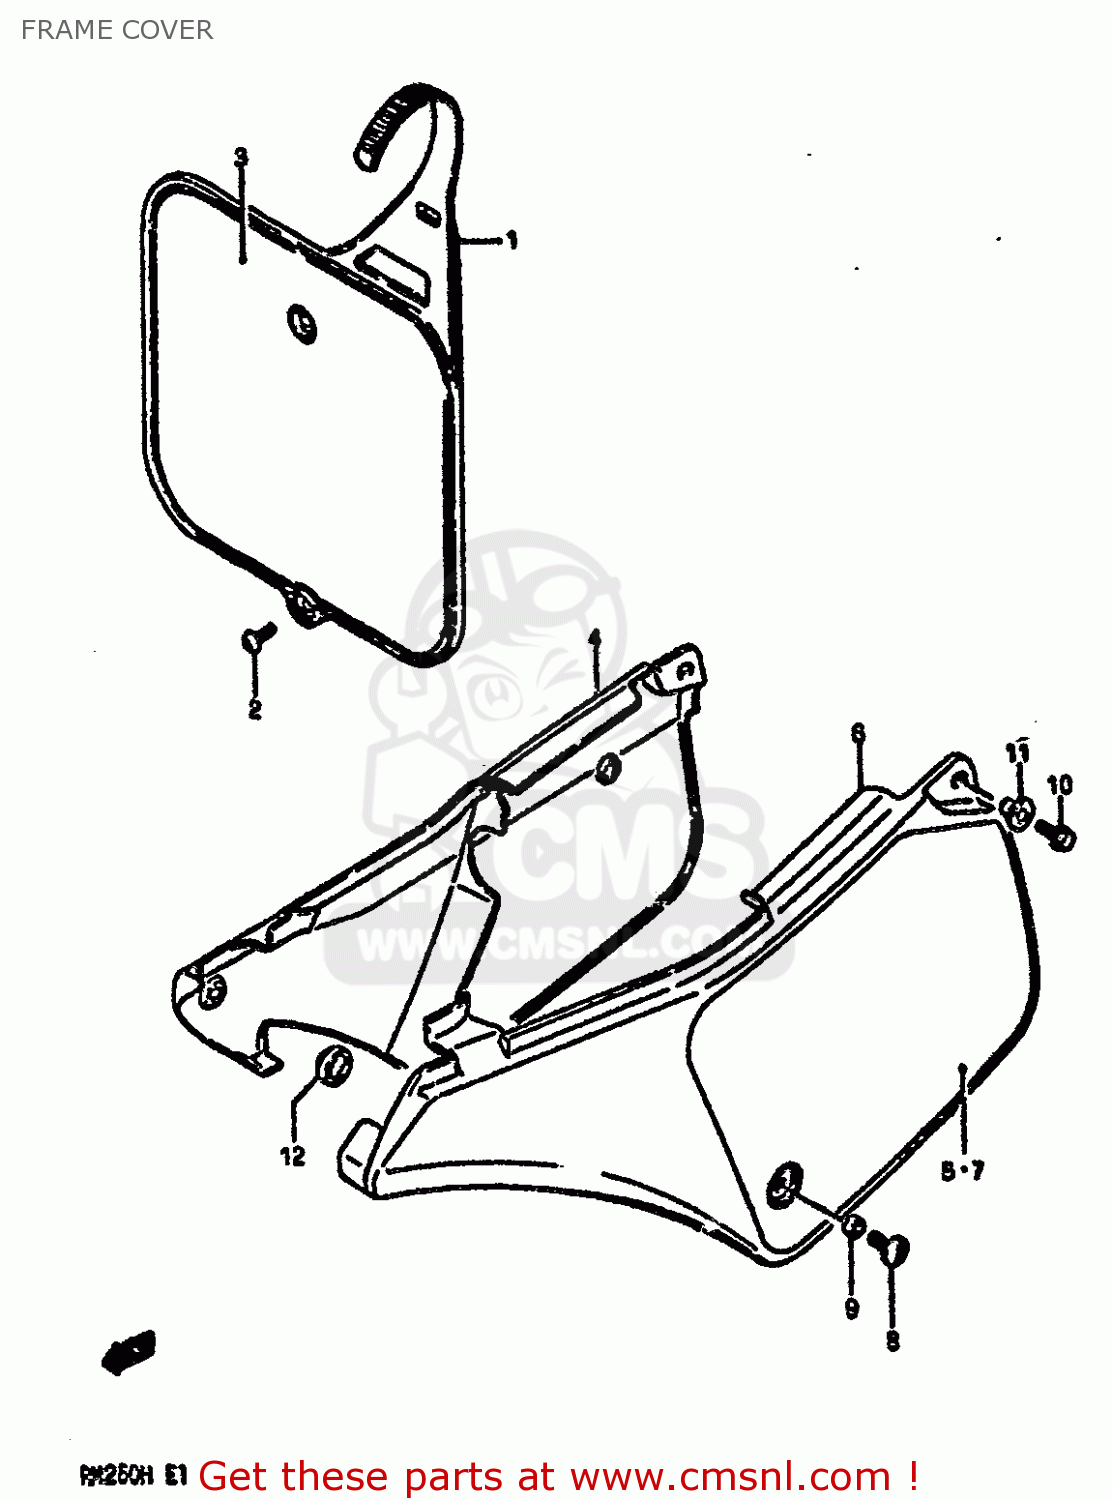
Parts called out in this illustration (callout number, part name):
1	PLATE,NUMBER,FRONT
2	SCREW
3	EMBLEM,FRONT NUMBER PLATE
4	COVER,FRAME,RIGHT
5	EMBLEM
6	COVER,FRAME,LEFT
7	EMBLEM,FRAME COVER,LEFT
8	SCREW(6X14)
9	SPACER (6.1X8X3.5)
10	BOLT
11	WASHER
12	CUSHION
